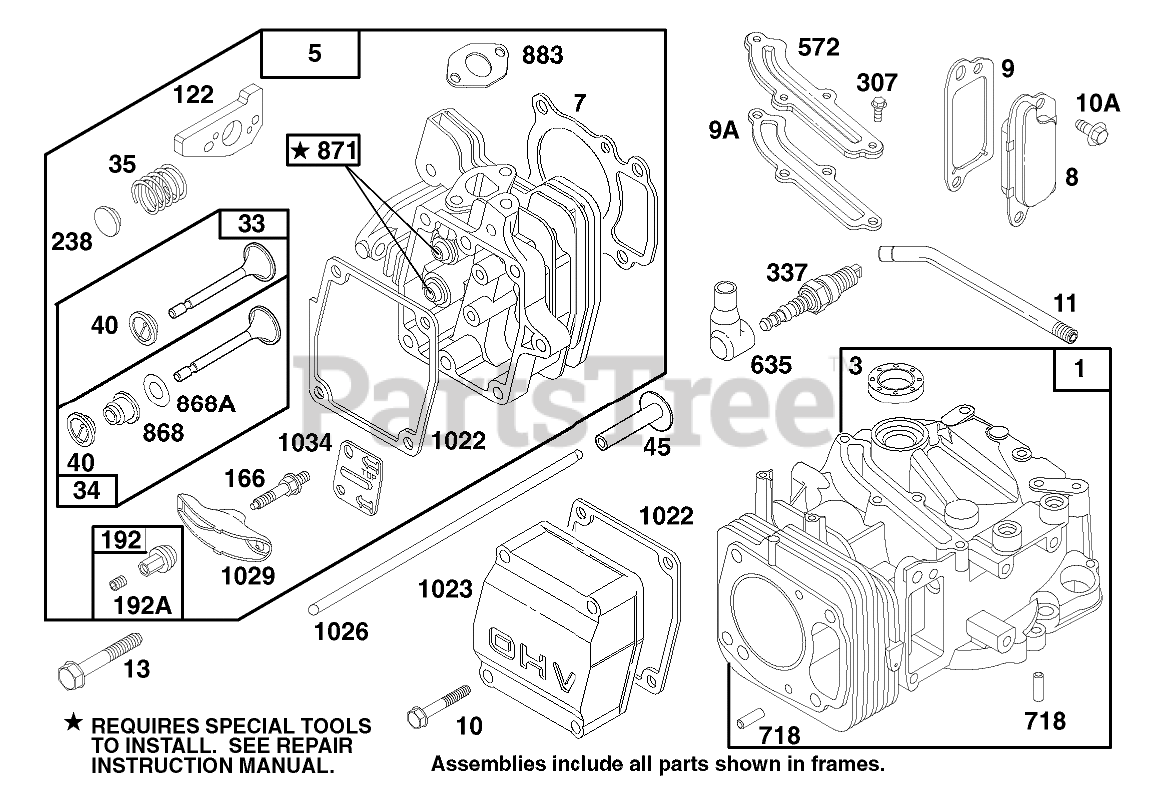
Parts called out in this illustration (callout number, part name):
1	CYLINDER ASSEMBLY
3	SEAL - OIL
5	CYLINDER HEAD
7	CYLINDER HEAD GASKET
8	Breather Assy
9	BREATHER GASKET
9A	GASKET-BREATHER
10	HEX HEAD SCREW
10A	HEX HEAD SCREW
11	TUBE - BREATHER
13	CYLINDER HEAD SCREW
33	EXHAUST VALVE
34	INTAKE VALVE
35	VALVE SPRING
40	SPRING RETAINER
45	VALVE TAPPET
122	ADAPTER ASSEMBLY
166	ROCKER ARM STUD
192	NUT - HEX SPECIAL
192A	SCREW SET
238	VALVE CAP
307	SCREW - SEM
337	PLUG-SPARK
572	BAFFLE - CYCLINDER
635	SPARK PLUG ELBOW
718	DOWEL - SLEEVE
868	SealAssy-Valve
868A	Seal-Valve
871	Bushing-Guide
883	EXHAUST GASKET
1022	ROCKER COVER GASKET
1023	COVER - VALVE
1026	PUSH ROD
1029	ROCKER ARM
1034	PUSH ROD GUIDE
